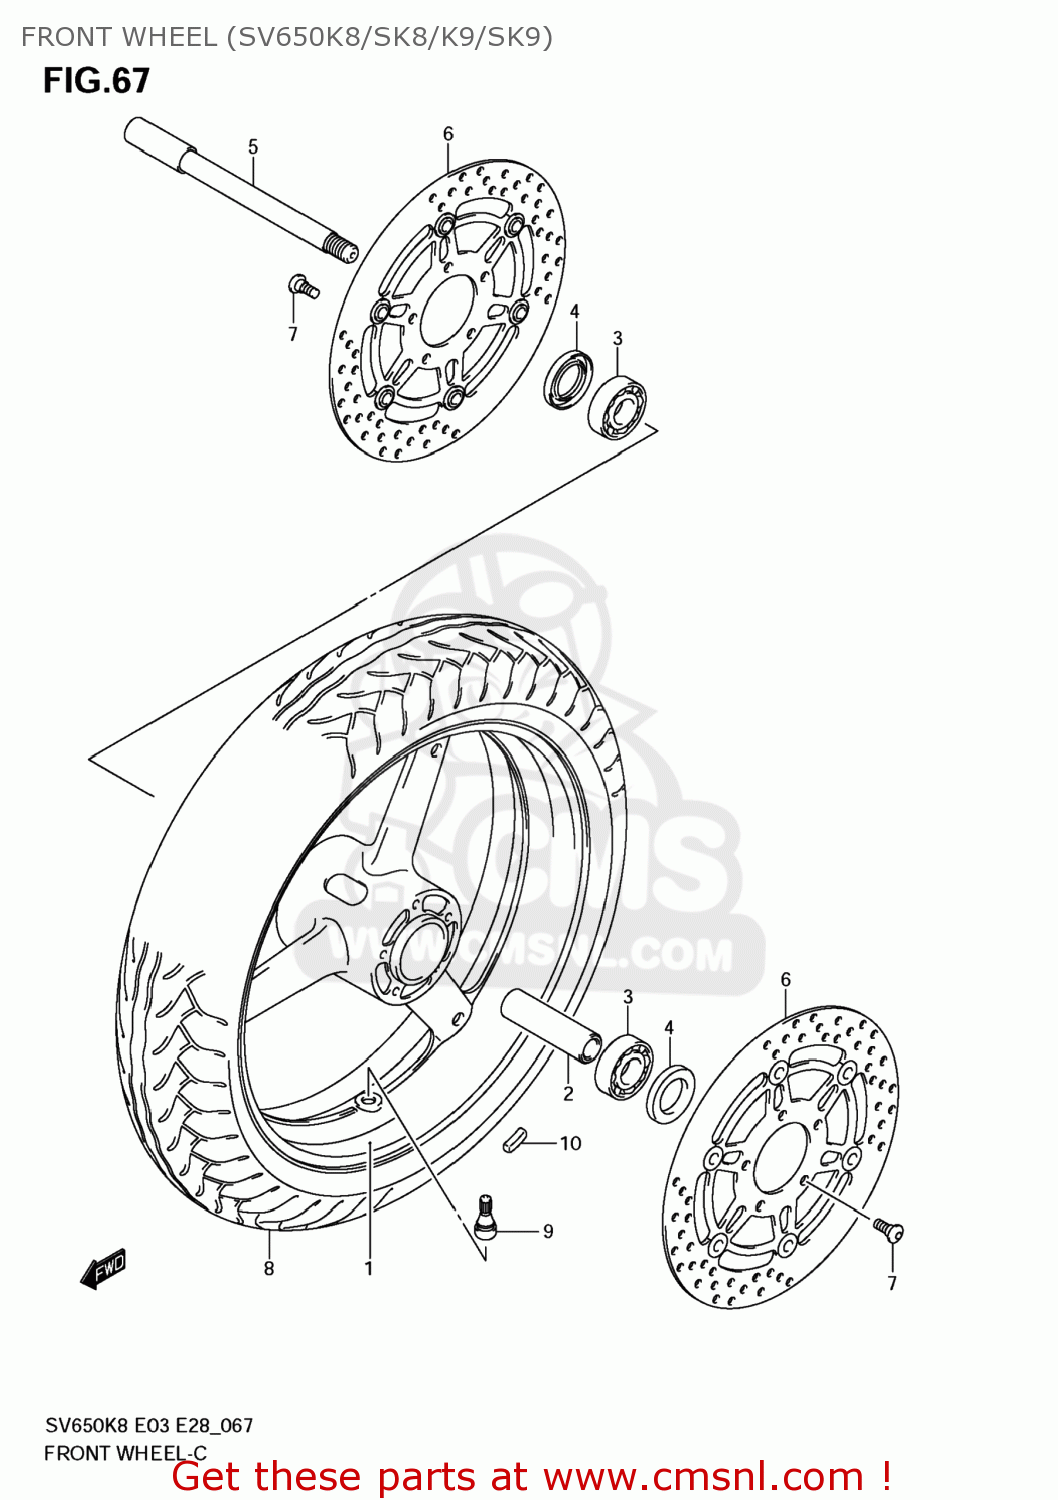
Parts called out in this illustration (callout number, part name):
1	WHEEL,FR(17M/CXMT3.50)
2	SPACER(17.5X25X88)
3	BEARING
4	SEAL,OIL(22X40X7)
5	AXLE,FR
6	DISC,FR BRAKE
7	BOLT(8X21)
8	TIRE,FR(120/60ZR17M/C 55W)
9	VALVE ASSY,WHEEL RIM(TR412)
10	BALANCER,WHEEL(10G)
